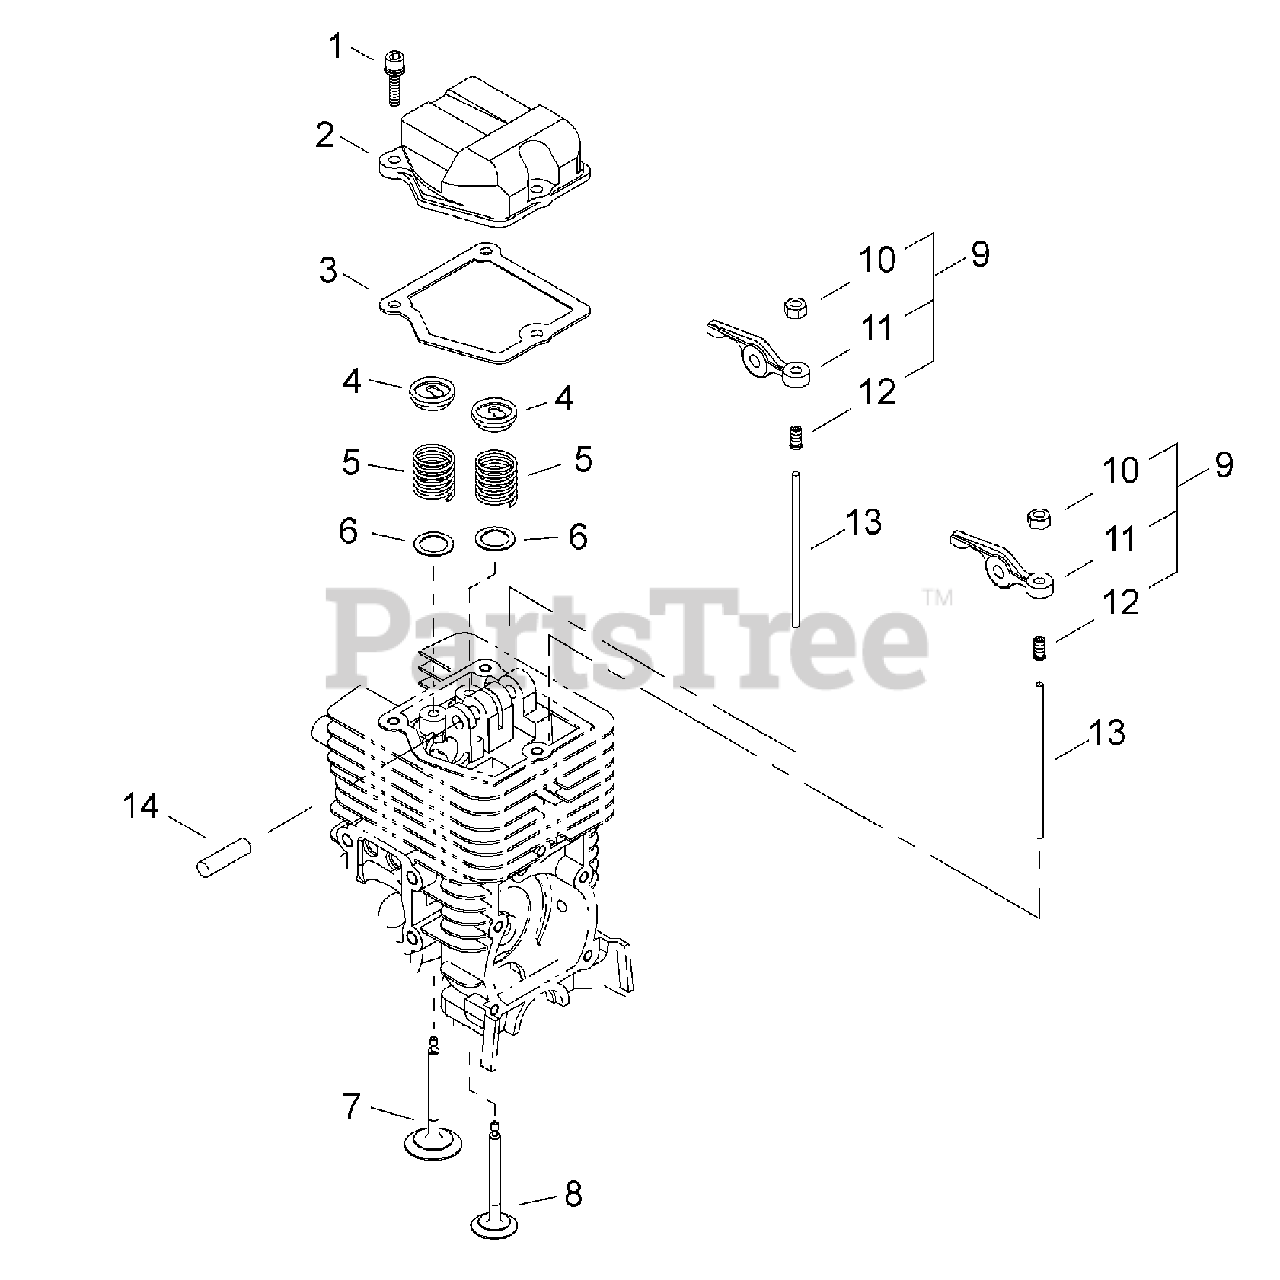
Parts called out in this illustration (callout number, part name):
1	SCREW - 4X12
2	COVER, ROCKER ARM
3	GASKET
4	RETAINER, VALVE
5	SPRING, VALVE
6	WASHER, VALVE - 9
7	VALVE, INTAKE
8	VALVE, EXHAUST
9	ROCKER ARM ASSY
10	LOCKNUT, ADJUSTER
11	ARM, ROCKER
12	SCREW, ADJUST
13	PUSHROD
14	SHAFT, ROCKER ARM - 5X31.8
